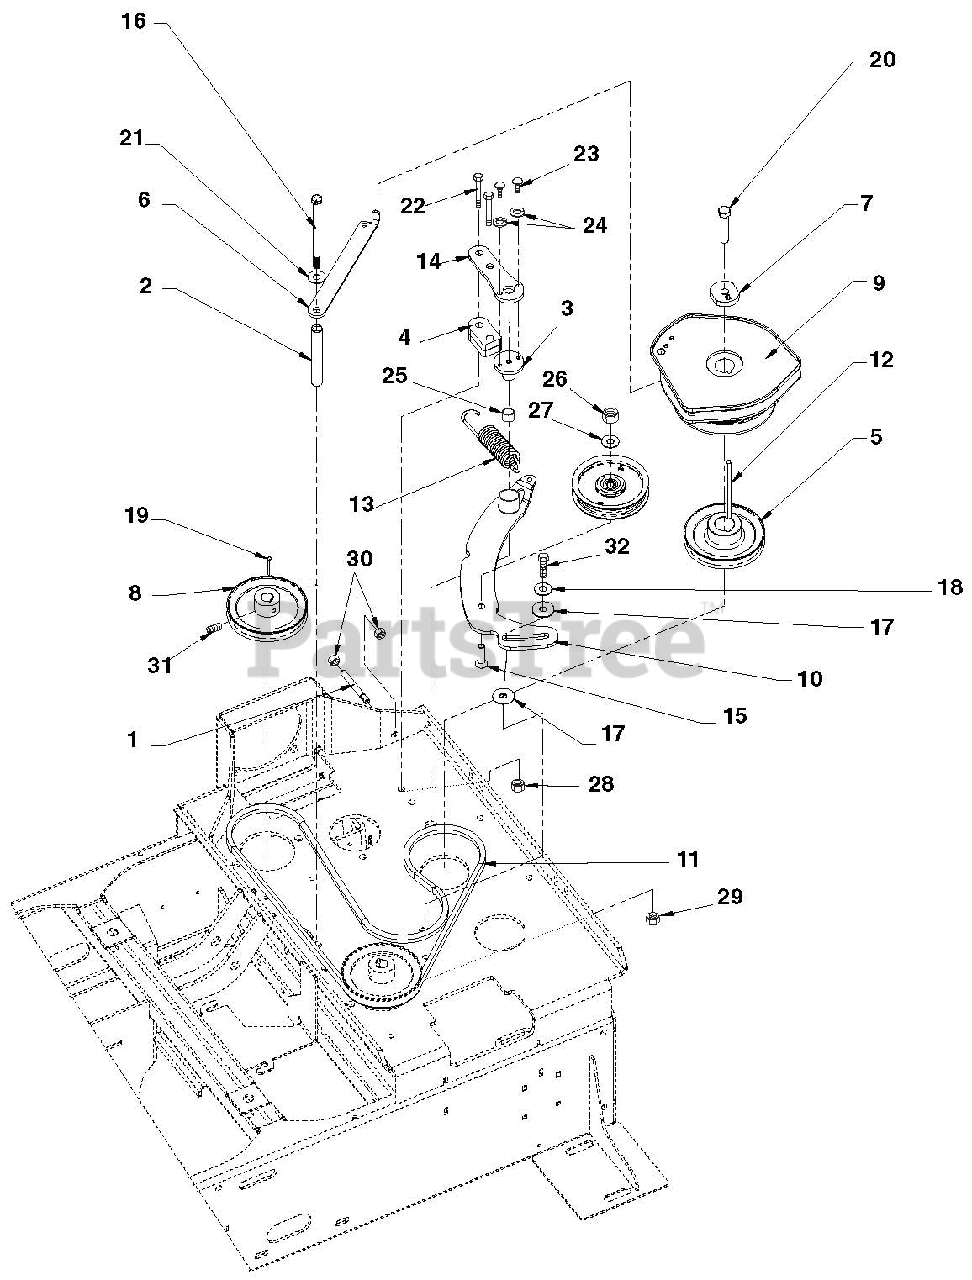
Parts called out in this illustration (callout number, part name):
1	ROD, THREADED ADJUSTMENT
2	TUBE, RD .625 X .120 X 4.50
3	PIN, TENSIONER PIVOT
4	PLATE, SPACER - PUMP TESIONER
5	PULLEY, V-BELT 5.00X1.13 W/KEY
6	PLATE, CLUTCH STOP
7	WASHER, CLUTCH UNIVERSAL
8	PULLEY, V-BELT 4.78X17MM W/KEY
9	CLUTCH, ELECT-OGURA, GT3.5
10	WLDT, Z PUMP BELT IDLER ARM
11	BELT, HA 64.2 EL AMD
12	KEY, .250 X .250 X 4.62 SQ
13	SPRING, EXT 1.19X.162X4.25 Y
14	PLATE, PUMP TENSIONER TOP
15	BOLT, 3/8-16X1.50 FLAT SOC Y
16	BOLT, 3/8-16X5.50 HEX 5 Y
17	WASHER, .400X1.27X.062 NYLON
18	WASHER, .406X1.00X.060 FLAT Y
19	KEY, M5 X M5 X M36 RD
20	BOLT, 7/16-20X2.25 HEX 5 Y
21	WASHER, .375 MED SPRG LOCK Y
22	BOLT, 3/8-16X2.00 HEX 5 Y
23	BOLT, 1/4-20X.500 HEX 5 Y
24	WASHER, .250 MED SPRG LOCK Y
25	BRG, SLV .753X.878X.750
26	LOCKNUT, 3/8-16 WHIZ Y
27	WASHER, .390X.750X.080 FLAT Y
28	LOCKNUT, 3/8-16 CROWN Y
29	LOCKNUT, 5/16-18 WHIZ Y
30	NUT, 3/8-16 STD HEX GR5 Y
31	SET SCREW, 5/16-18X.625 SQ CUP
32	BOLT, 3/8 X.500X5/16-18 SLD Y
